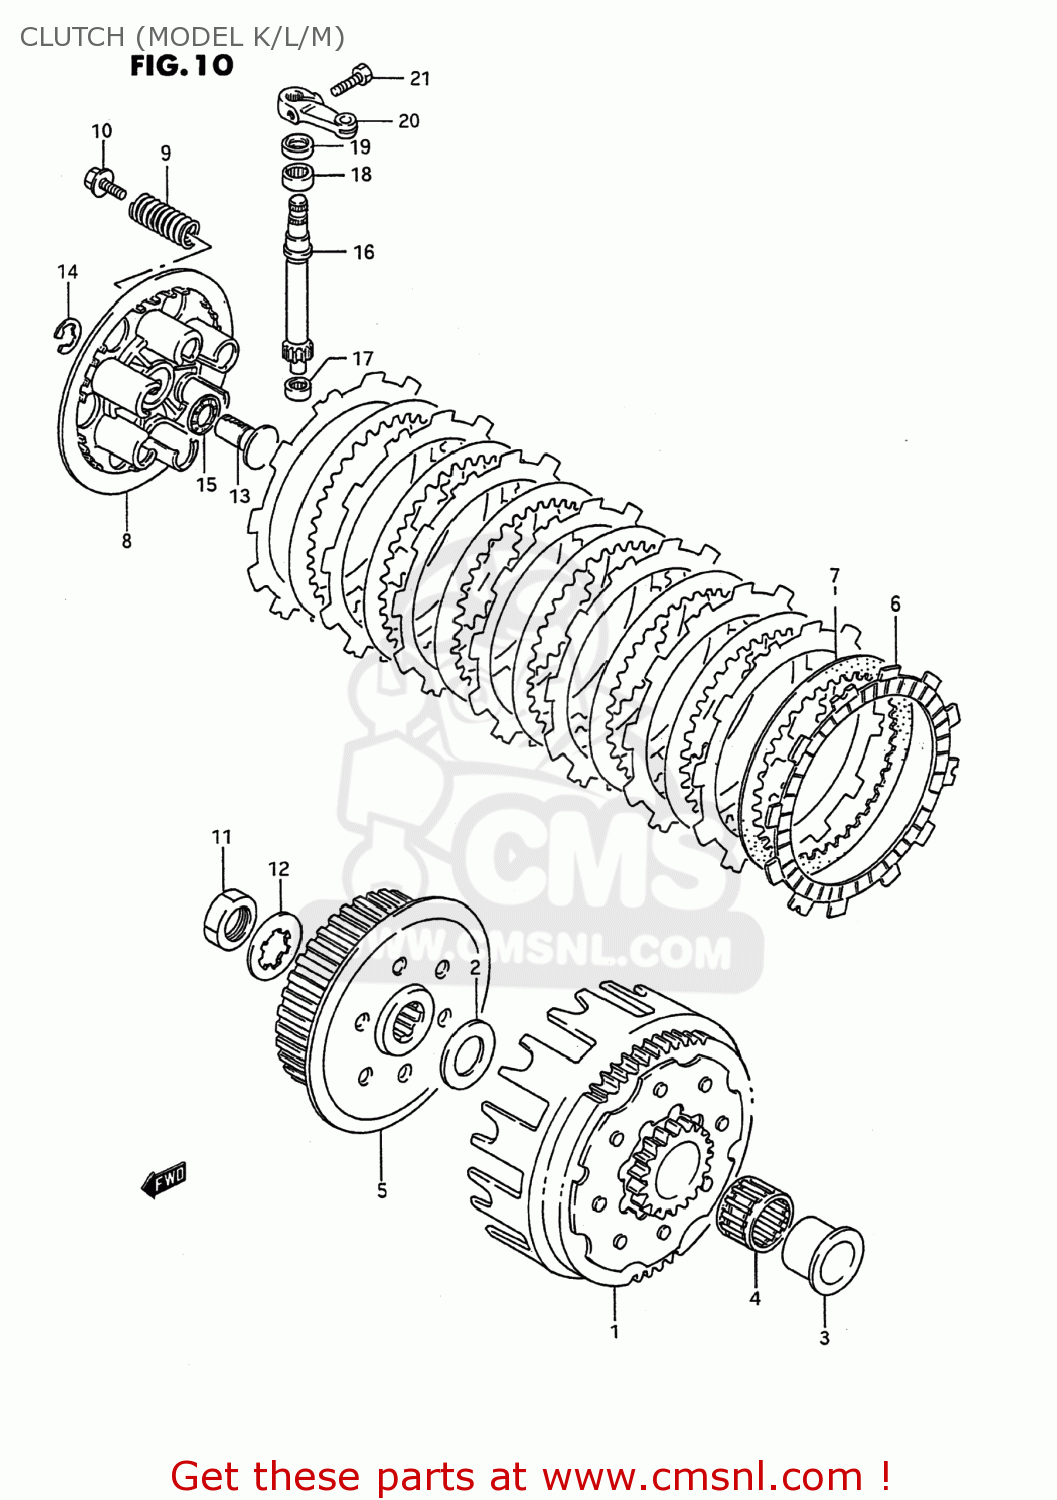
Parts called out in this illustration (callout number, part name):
1	GEAR ASSEMBLY,PRIMARY DRIVEN,N
2	WASHER(22X38X2)
3	SPACER,PRIMARY DRIVEN GEAR
4	BEARING
5	HUB,CLUTCH SLEEVE
6	PLATE,CLUTCH DRIVE (NAS)
7	PLATE,CLUTCH DRIVEN (NAS)
8	DISC,CLUTCH PRESSURE
9	SPRING
10	BOLT(5X18)
11	NUT
12	WASHER,LOCK
13	RACK,CLUTCH RELEASE
14	E RING
15	BEARING(10X22X2.8)
16	PINION,CLUTCH RELEASE(NT:12)
17	BEARING(9X13X10)
18	BEARING(12X16X10)
19	SEAL,OIL(10X17X5)
20	ARM,CLUTCH RELEASE
21	BOLT
